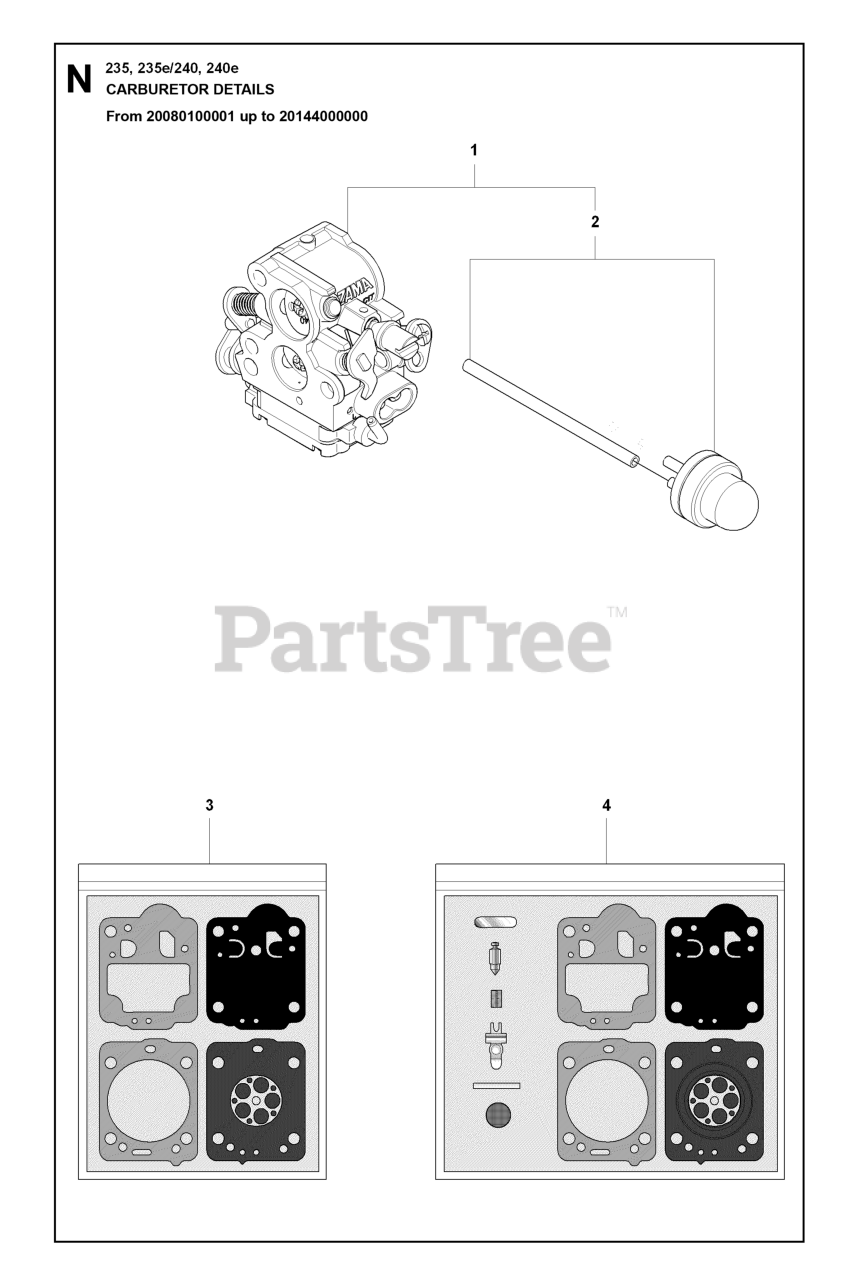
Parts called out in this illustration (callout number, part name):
1	CARBURETTOR 14MM AIR BORE, ANG
2	PURGE & LINE ASSY
3	KIT CARB GASKET
4	KIT CARB REPAIR
